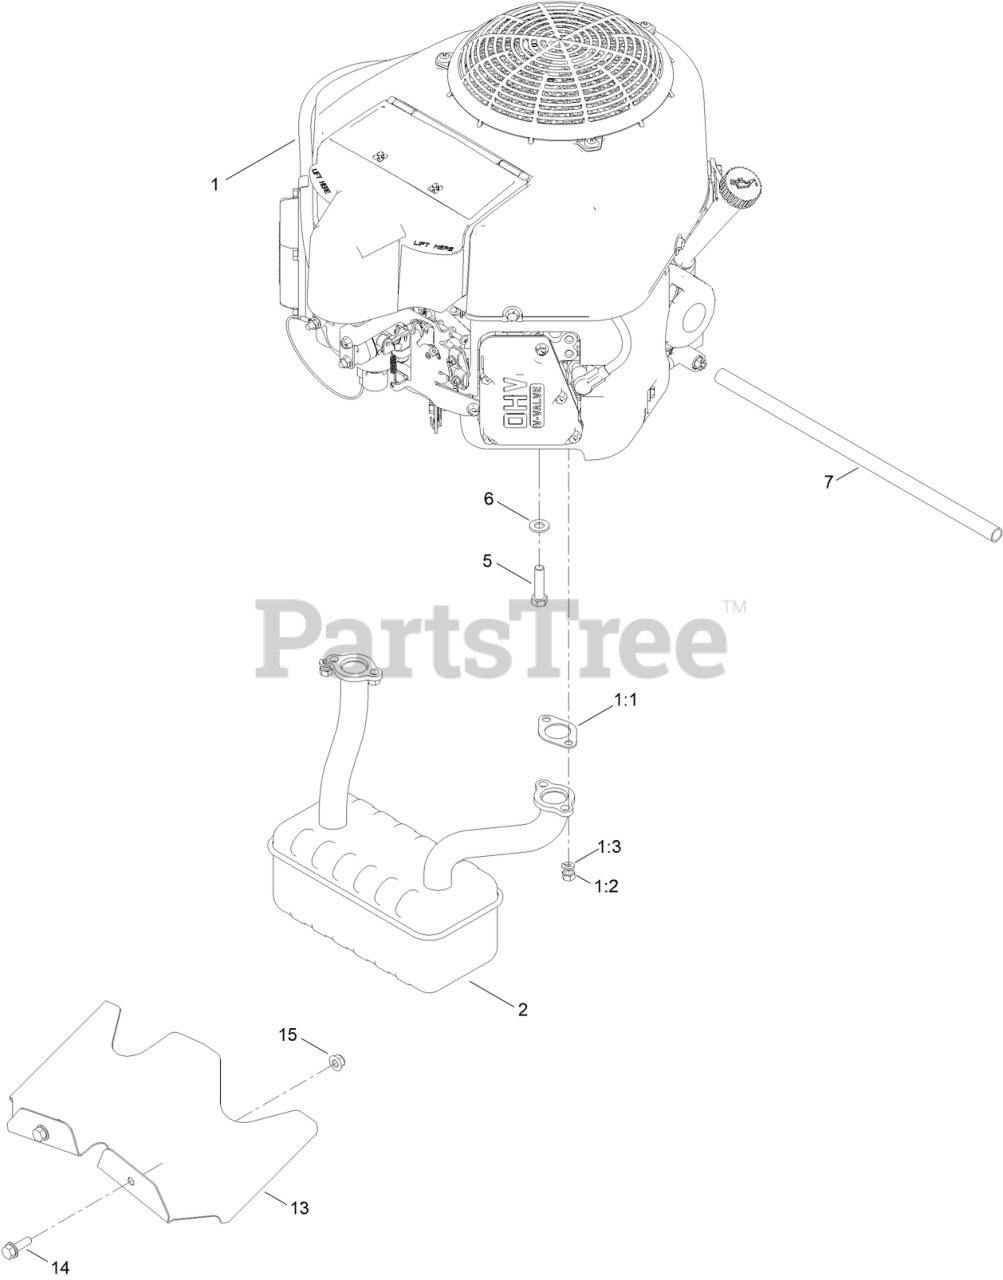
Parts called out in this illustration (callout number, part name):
1:1	GASKET-EXHAUST
1:3	WASHER-LOCK
2	MUFFLER
5	SCREW-HWH, THD ROLL
6	WASHER-FLAT
7	TUBE-DRAIN, OIL
13	SHIELD-HEAT
14	SCREW-HHF
15	NUT-HF
